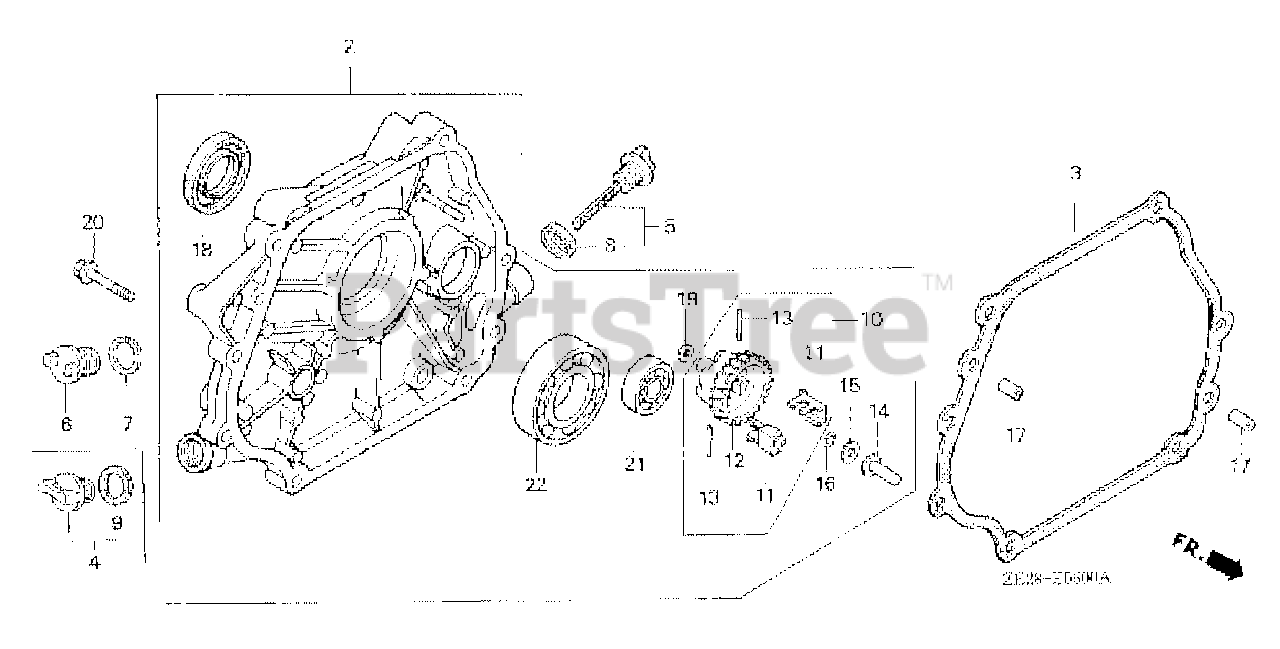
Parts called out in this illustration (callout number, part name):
2	COVER ASSY., CRANKCASE (S-TYPE)(BALANCER)
3	GASKET, CASE COVER
4	CAP ASSY., OIL FILLER
5	CAP ASSY., OIL FILLER
6	CAP, OIL FILLER
7	GASKET, OIL FILLER CAP
8	GASKET, OIL FILLER CAP
9	GASKET, OIL FILLER CAP
10	GOVERNOR ASSY. (BALANCER)
11	WEIGHT, GOVERNOR
12	HOLDER, GOVERNOR WEIGHT
13	PIN, GOVERNOR WEIGHT
14	SLIDER, GOVERNOR
15	WASHER (6X16)
16	CLIP, GOVERNOR HOLDER
17	PIN, DOWEL (8X12)
18	OIL SEAL (30X46X8)
19	WASHER, PLAIN (6MM)
20	BOLT, FLANGE (8X35)
21	BEARING, RADIAL BALL (6202)
22	BEARING, RADIAL BALL (6206)
